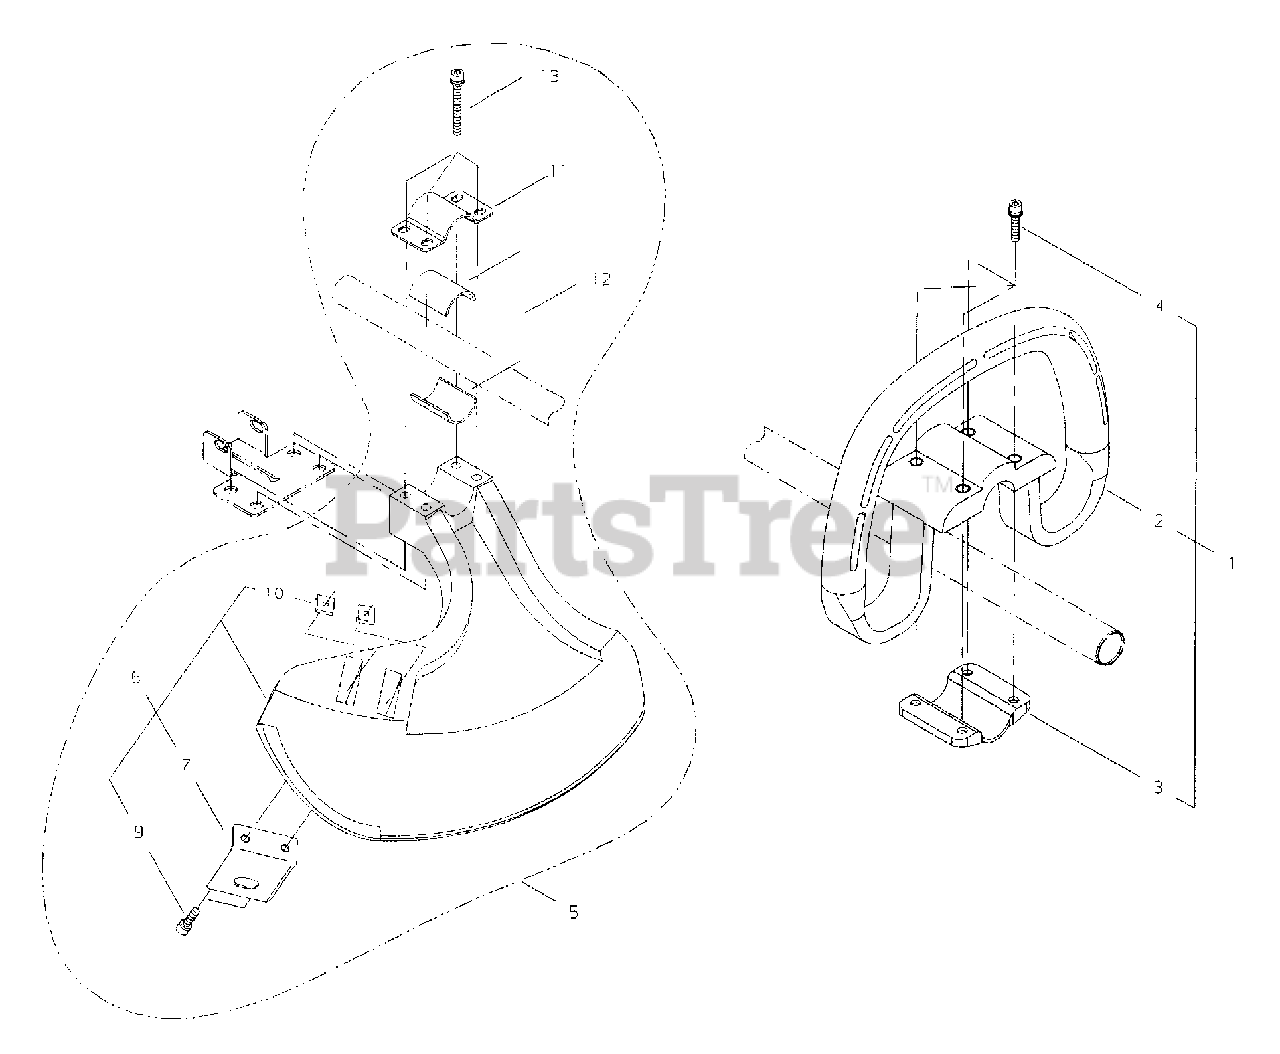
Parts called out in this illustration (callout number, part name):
1	HANDLE ASSY
2	HANDLE, SUPPORT
3	BOLT M5×35
4	NUT M5
5	DEBRIS SHIELD KIT
6	DEBRIS SHIELD ASSY
7	CUTTER
9	BOLT M5×16
10	CUTTER
11	CLAMP, UPPER
12	SPACER
13	BOLT M5×45
